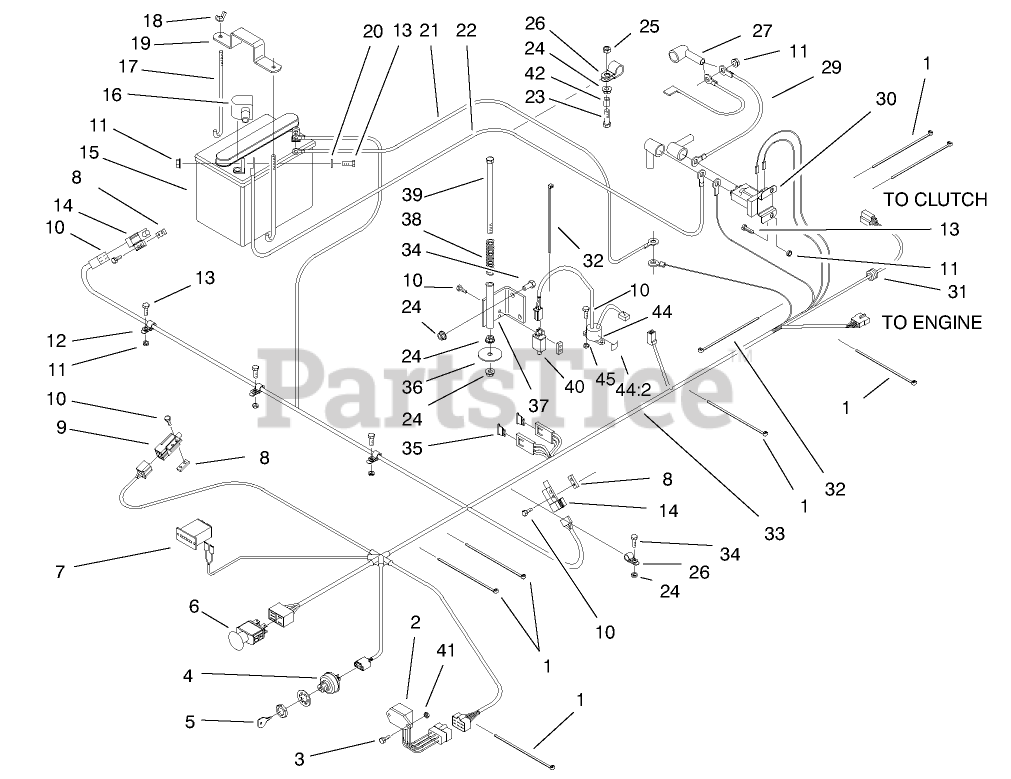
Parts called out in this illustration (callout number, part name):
1	Tie-Plastic
2	Module-Safety
3	Bolt-CARR
4	Ignition Switch
5	KEY-IGNITION
6	Switch
7	Meter-Hour
8	Plate
9	Switch-Brake
10	SCREW-HEAD, PAN
11	NUT-HF
12	Clip
13	SCREW-HH
14	Switch-Drive Lever
15	Battery
16	Insulator Battery
17	Bolt
18	Wingnut
19	Strap-Hold Down
20	WASHER-FLAT
21	Cable-Ground
22	Wire
23	Bolt-TAP
24	NUT-HF
25	Nut-Lock
26	Clip
27	Insulator Solenoid
28	Wire-Starter Solonoi
29	Wire-Starter
30	Switch-Solenoid
31	Grommet
32	Tie-Plastic
33	Harness-Wiring
34	SCREW-HH
35	Fuse
36	Wahser
37	Bracket-Switch, Seat
38	Spring
39	Screw
40	Switch-Seat
41	NUT-LOCK, NI
42	Bushing
44	Switch-Tilt
44:2	Decal
45	NUT-LOCK, NI
